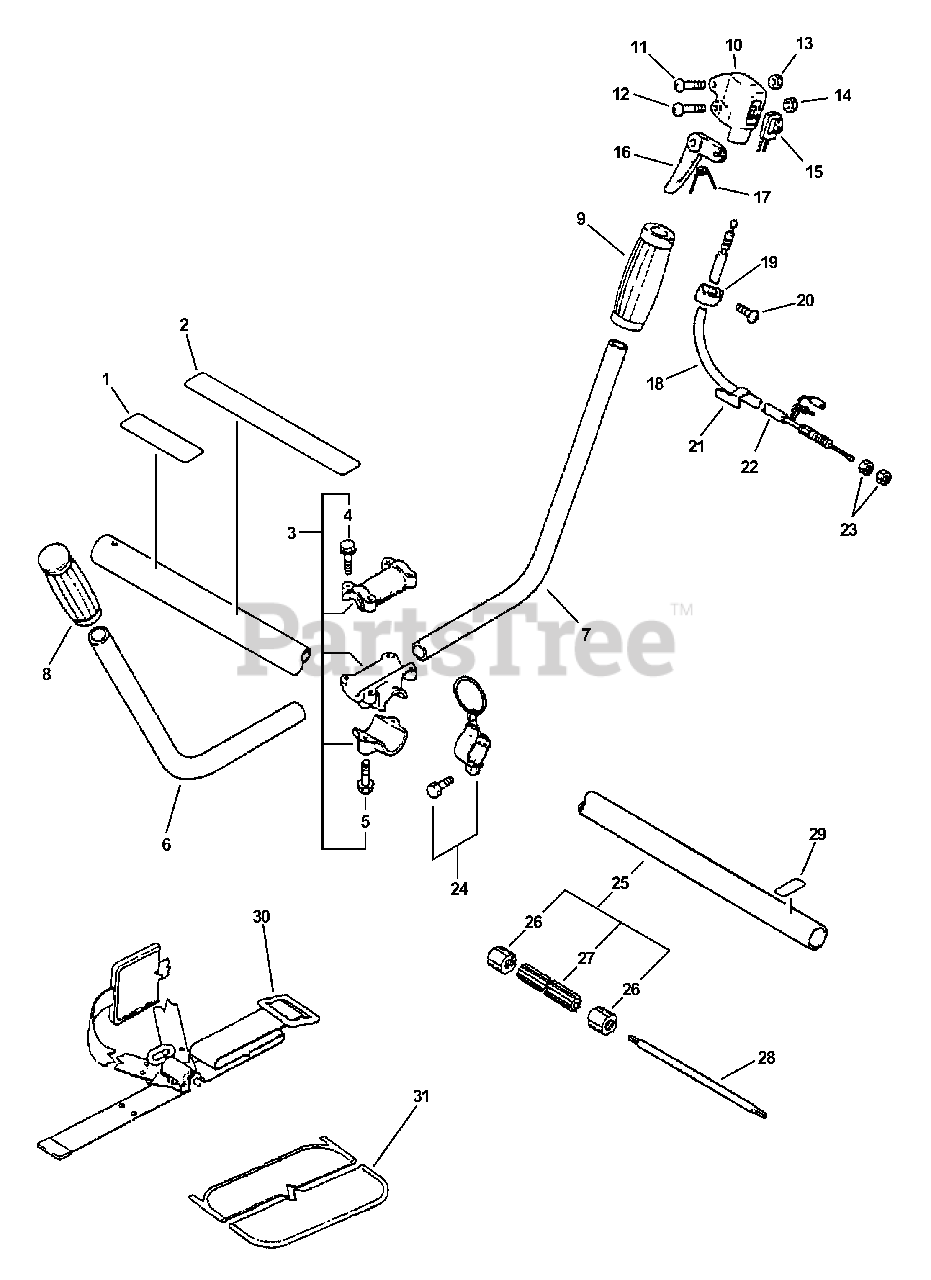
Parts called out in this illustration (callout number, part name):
1	LABEL - CAUTION
2	LABEL - CAUTION
3	HANDLE BRACKET KIT
4	BOLT - 5X25
5	BOLT - 6X30
6	HANDLE, FRONT - LEFT
8	GRIP, HANDLE - LEFT
9	GRIP, HANDLE
10	BRACKET, THROTTLE CONTROL
11	SCREW - 5X25
12	SCREW - 5X30
13	LOCKNUT - 5
15	IGNITION SWITCH ASSY
16	TRIGGER, THROTTLE
17	SPRING, TRIGGER
18	CABLE, THROTTLE
20	SCREW - 5X10
22	TUBE
24	HANGER KIT
25	MAIN PIPE ASSY
27	LINER - FLEXIBLE
28	DRIVESHAFT - FLEXIBLE
29	LABEL - ALIGNMENT
30	SHOULDER STRAP ASSY
31	CUSHION
